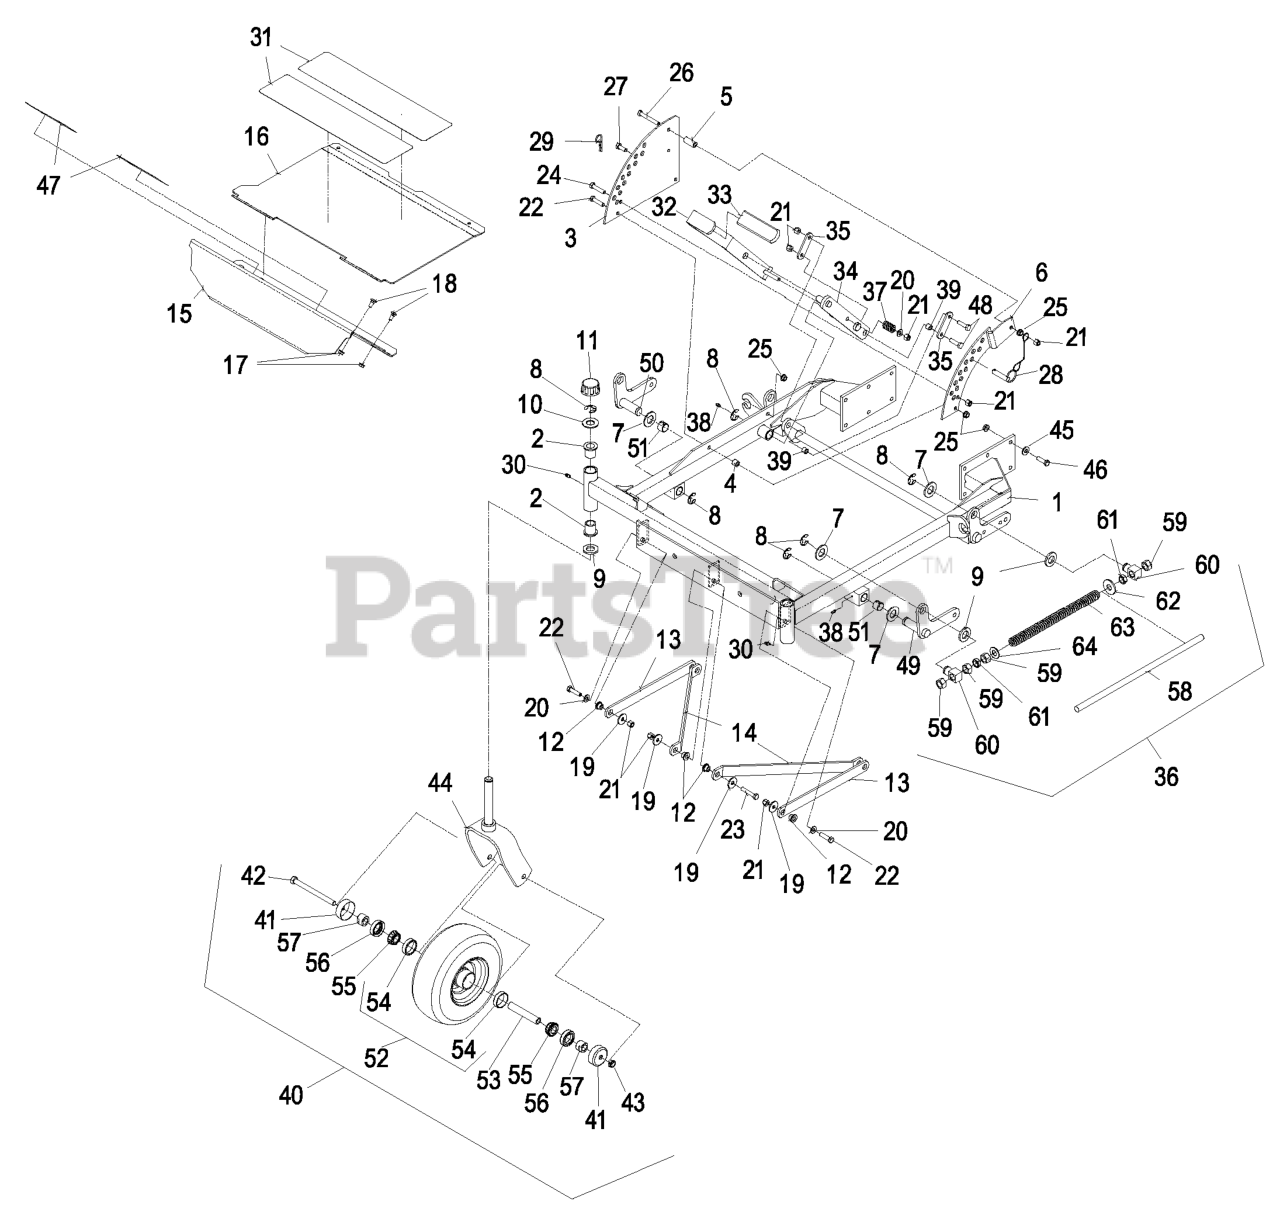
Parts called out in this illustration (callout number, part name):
2	BEARING-FLANGED
3	PLATE-LIFT, DECK
4	BUSHING-LEVER, LIFT
5	BUSHING-LEVER, LIFT
6	PLATE-LIFT, DECK
7	WASHER-FLAT
8	RING-RETAINING, EXT
9	WASHER-FLAT
11	CAP-HUB
12	SPACER-STRUT
15	Asm, Floorpan (103-4033-01) W/Decals & Pads
16	ASM,FLOORPAN
18	BOLT-CARR
20	WASHER-FLAT
21	NUT-LOCK, NI
22	SCREW-HH
23	SCREW-HH
24	SCREW-HH
25	NUT-HHF, WHIZ
26	SCREW-HH
27	SCREW-HH
28	PIN-HITCH (W/LANYARD)
29	PIN-COTTER
30	FITTING-GREASE
31	PAD-ANTISKID
32	ASM, LIFT LEVER / GRIP
33	GRIP-LEVER, LIFT
34	WLD, DECK LIFT ARM-LHP
35	ARM-LIFT, DECK
36	FRONT SPRING ASM
37	SPRING-COMPRESSION
38	FITTING-GREASE
39	BUSHING
40	WHEEL AND TIRE ASM
41	GUARD-SEAL
42	SCREW-HH
43	NUT-HEX
44	WLD,CASTER FORK
45	WASHER-BELLEVILLE
46	SCREW-HH
47	PAD-ANTI SKID
48	SCREW-HH
49	WLD,SHAFT LH
50	WLD,SHAFT RH
51	BUSHING,SPRING
54	CUP-BEARING
55	BEARING-CONE, TAPERED ROLLER
56	SEAL-CASTER
57	SPACER-NUT
58	ROD-LIFT, DECK
59	NUT-HEX
60	SWIVEL-DECK MOUNT, REAR
61	NUT-JAM
63	SPRING-COMPRESSION
64	WASHER-FLAT
